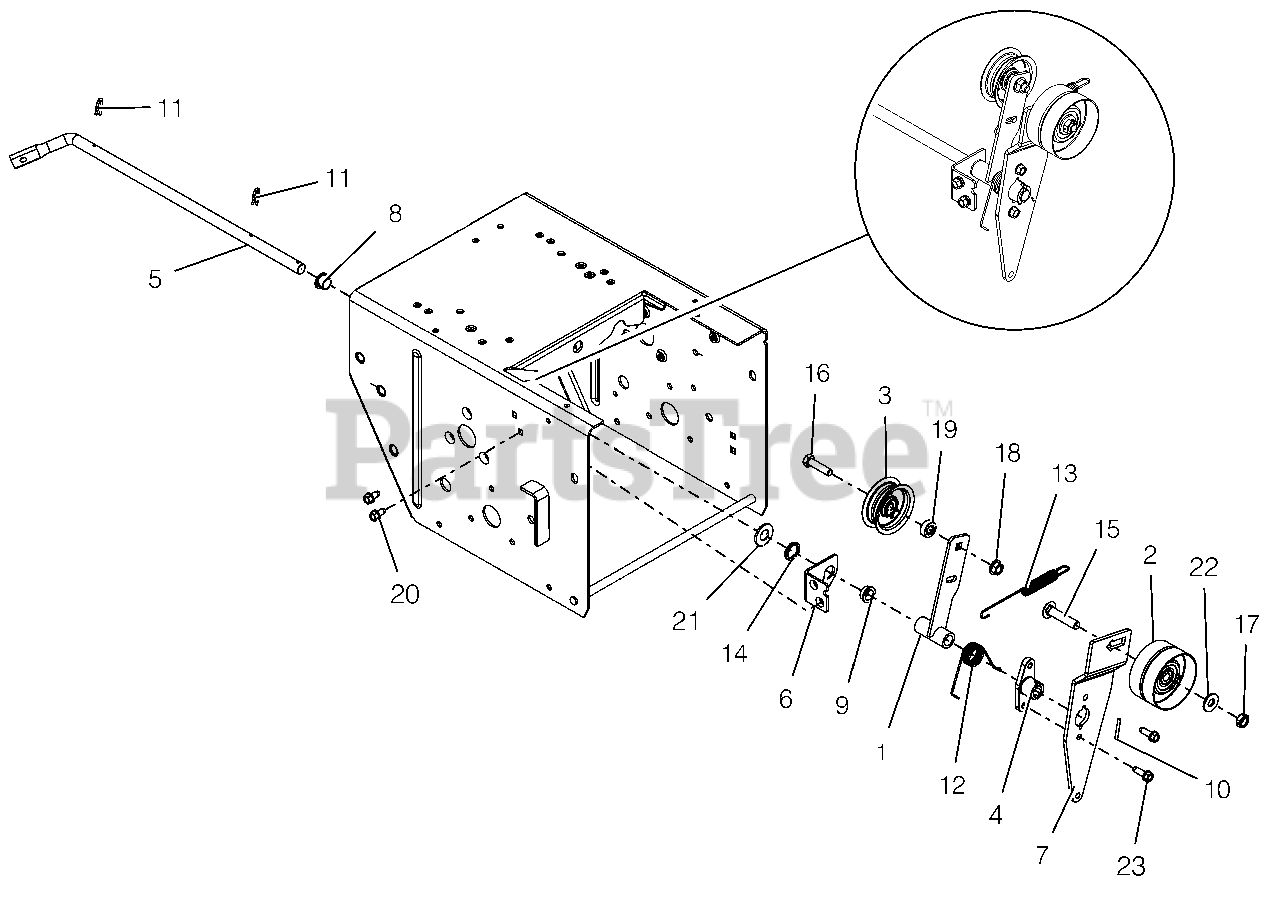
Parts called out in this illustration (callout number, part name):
1	ARM, IDLER-TRACTION
2	IDLER, FLAT-2.75 OD X .375 ID
3	IDLER, FLAT - 2.00"
4	HUB, BRAKE ARM
5	ARM, ATTACHMENT
6	BRACKET, SUPPORT
7	ARM, IDLER-ATTACHMENT
8	BUSHING, POLYLINER-.50 SPLIT
9	BSHG,FLANGE .500X.625X.270X.75
10	PIN-ROLL .125X1.00
11	CLIP, SPRING
12	SG-TORS .067X.88
13	SG-TENS .06X.482X5.35
14	WAVE SPRING .600X.875X.25FH
15	BLT-RHDSSQNK .38-16X1.75 G5YZ
16	@BLT-HEX .31-18X1.25 GR5 YWZC
17	@NUT-LK-CTR-JAM .375-16 YWZC
18	@NUT-LK-TOP-FLG .31-18 YWZC
19	SPCR, BRG .315X.500X.358X.281
20	SCR-TAP .25-20X.50 HWH TR YWZ
21	@WSHR-FL-STL.531X1.06X.095YWZC
22	@WSHR-FL-STL.38X.875X.083 YWZC
23	SCR-TAP-PM .25-20X.75 TR YWZ
